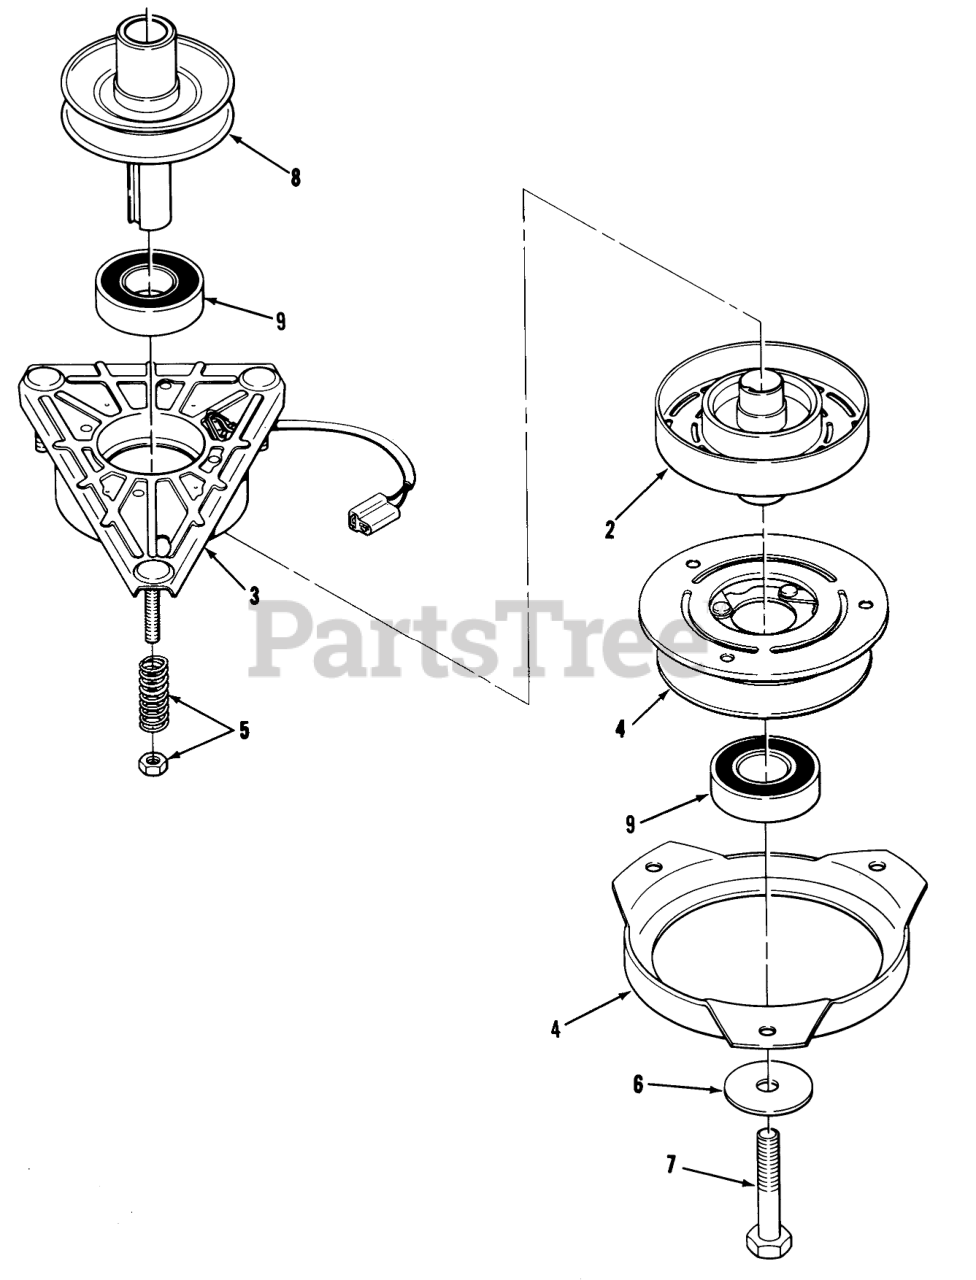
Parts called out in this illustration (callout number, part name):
1	Electric Clutch Assembly (Incl. Ref. #2-5)
2	ASS'Y-ROTOR
3	Field Assembly (Incl. Ref. #9)
4	Armature & Pulley Assy. (Incl. Ref. #9)
5	ACCESS SPRING & NUT
6	WASHER
7	HHCS M10X1.5X120
8	PULLEY-ENGINE
9	BEARING-ELEC CLUTCH
